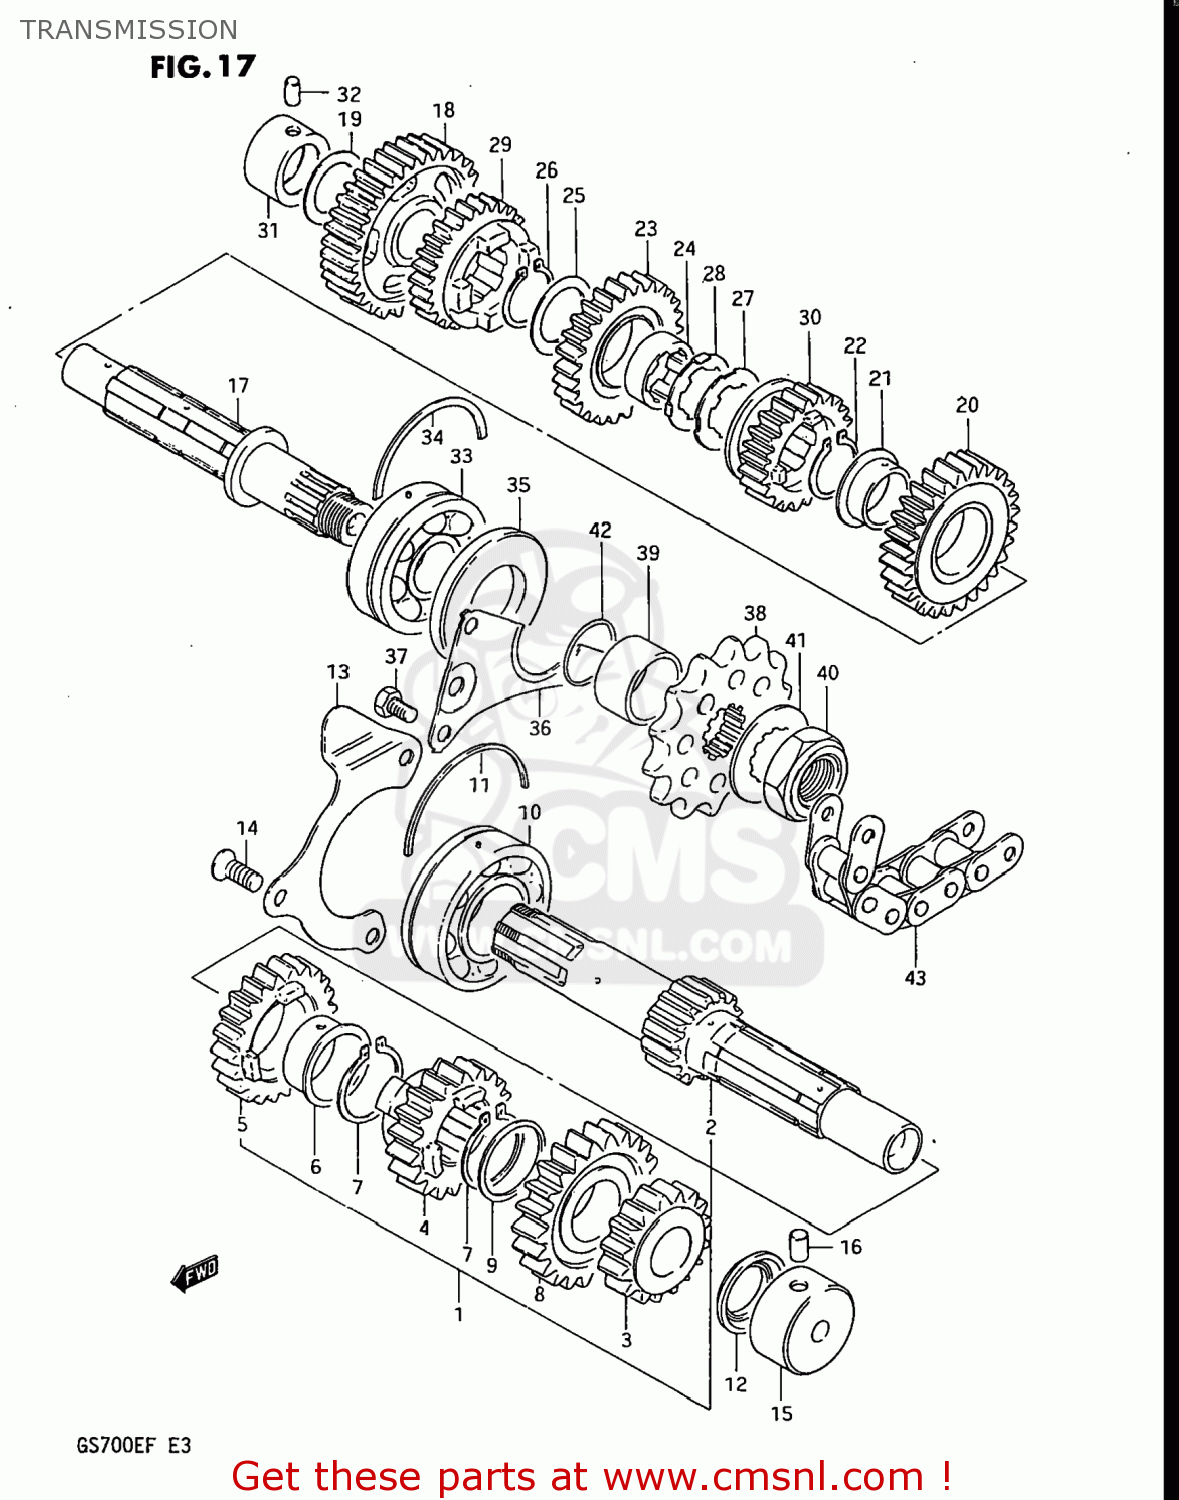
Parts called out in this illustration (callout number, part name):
1	SHAFT,COUNTER
2	SHAFT,COUNTER
3	GEAR,SECOND DRIVE
4	GEAR,THIRD DRIVE
5	GEAR,FOURTH DRIVE
6	BUSHING
7	RING,SNAP
8	GEAR,FIFTH DRIVE (NT:23)
9	WASHER,LOCK
10	BEARING(25X62X17)
11	C-RING
12	SEAL,OIL(20X31.2X2.7)
13	PLATE,COUNTERSHAFT BEARING
14	SCREW
15	BEARING(20X34X17.5)
16	PIN
17	SHAFT,DRIVE
18	GEAR,1ST DRIVEN(NT:35)
19	WASHER
20	GEAR,2ND DRIVEN(NT:28)
21	BUSH(28X32X2)
22	CIRCLIP
23	GEAR,THIRD DRIVEN
24	BUSH,3RD DRIVEN GEAR
25	WASHER,LOCK
26	CIRCLIP
27	WASHER,LOCK
28	WASHER
29	GEAR,4TH DRIVEN(NT:26)
30	GEAR,5TH DRIVEN(NT:22)
31	BEARING(20X34X20)
32	PIN
33	BALL BEARING 25X62X17
34	C-RING
35	SEAL,OIL(33X62X7)
36	PLATE,DRIVESHAFT OIL
37	BOLT
38	SPROCKET,ENGINE
39	SPACER (25X33X20.1)
40	NUT
41	WASHER
42	O RING(D:1,ID:24.5)
43	CHAIN ASSEMBLY,DRIVE
